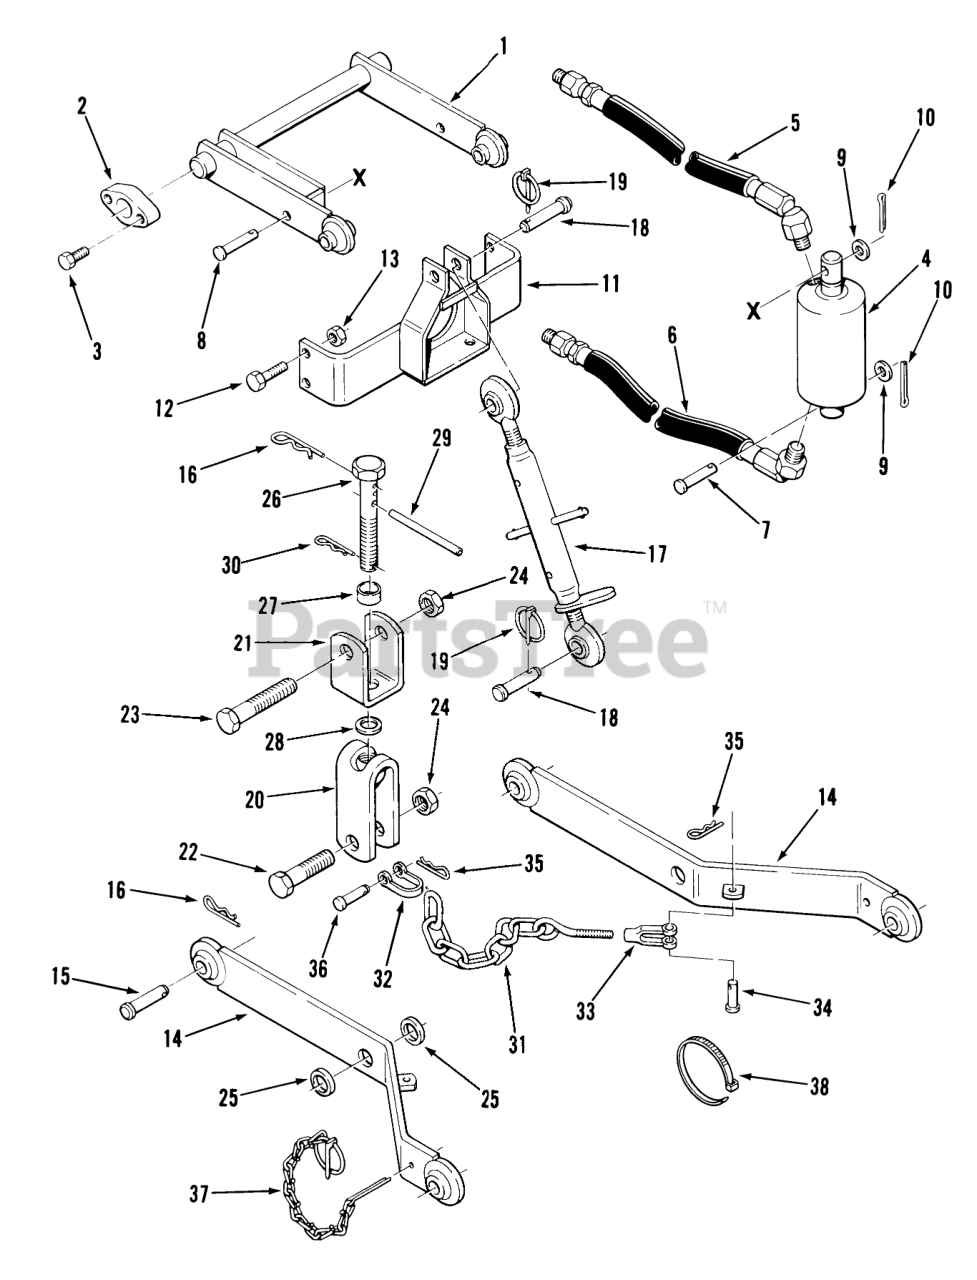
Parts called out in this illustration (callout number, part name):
1	LIFT BAR ASSEMBLY R
2	BLOCK
3	BOLT
4	Cylinder
5	ASSY HOSE HYD
6	ASSY HOSE HYD
7	Pin
8	Clevis Pin 1/2 x 2 3/4
9	Washer
11	ASSY UPPER LINK PIVO
12	Bolt
13	NUT
14	ASSY LOWER HITCH LNK B
15	PIN 5/8 DIA LINK ATT
16	Hairpin
17	Link-Upper
18	PIN HITCH UPPER LINK
19	HITCH PIN ASSY
20	Adjuster
21	LIFT BAR
22	Bolt 3/-10 x 3
23	Bolt 3/-10 X 3 1/2
24	E.S. Nut 3/4-10
25	SPACER
26	Adjusting Bolt
27	Spacer
28	WASHER
29	PIN
30	Hairpin Cotter
31	Sway Chain
32	Clevis
33	CLEVIS
34	PIN
36	Clevis Pin
37	Klik Pin
38	PLASTIC TIE
